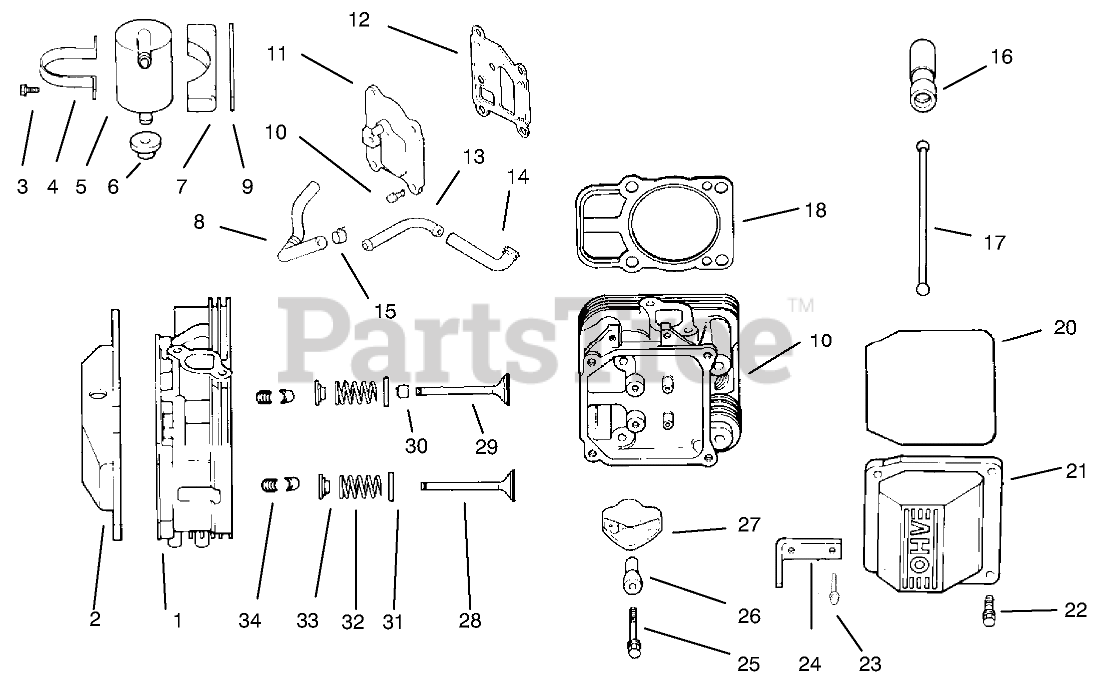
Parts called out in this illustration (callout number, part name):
1	#1 Cyl. Head Asm
2	Cover-Rocker
3	Kit-Breather INC 4
4	Grommet-Rubber
5	Cover-Breather
6	Screw
7	Hose-Breather
8	Retainer Kit
9	Cap-Spring, Valve
10	Spring-Valve
11	Retainer-Spring
12	Valve-Exhaust
13	Valve-Intake
14	Seal-Stem, Valve
15	Fitting
16	Hose-Breather
17	Lifter-Valve
18	Rod-Push
19	Gasket-Cylinder Head
20	#2 Cyl. Head Asm,
21	Arm-Rocker
22	Pivot-Rocker Arm
24	Cover-Rocker
25	Screw
26	Screw
27	Strap-Lifting
